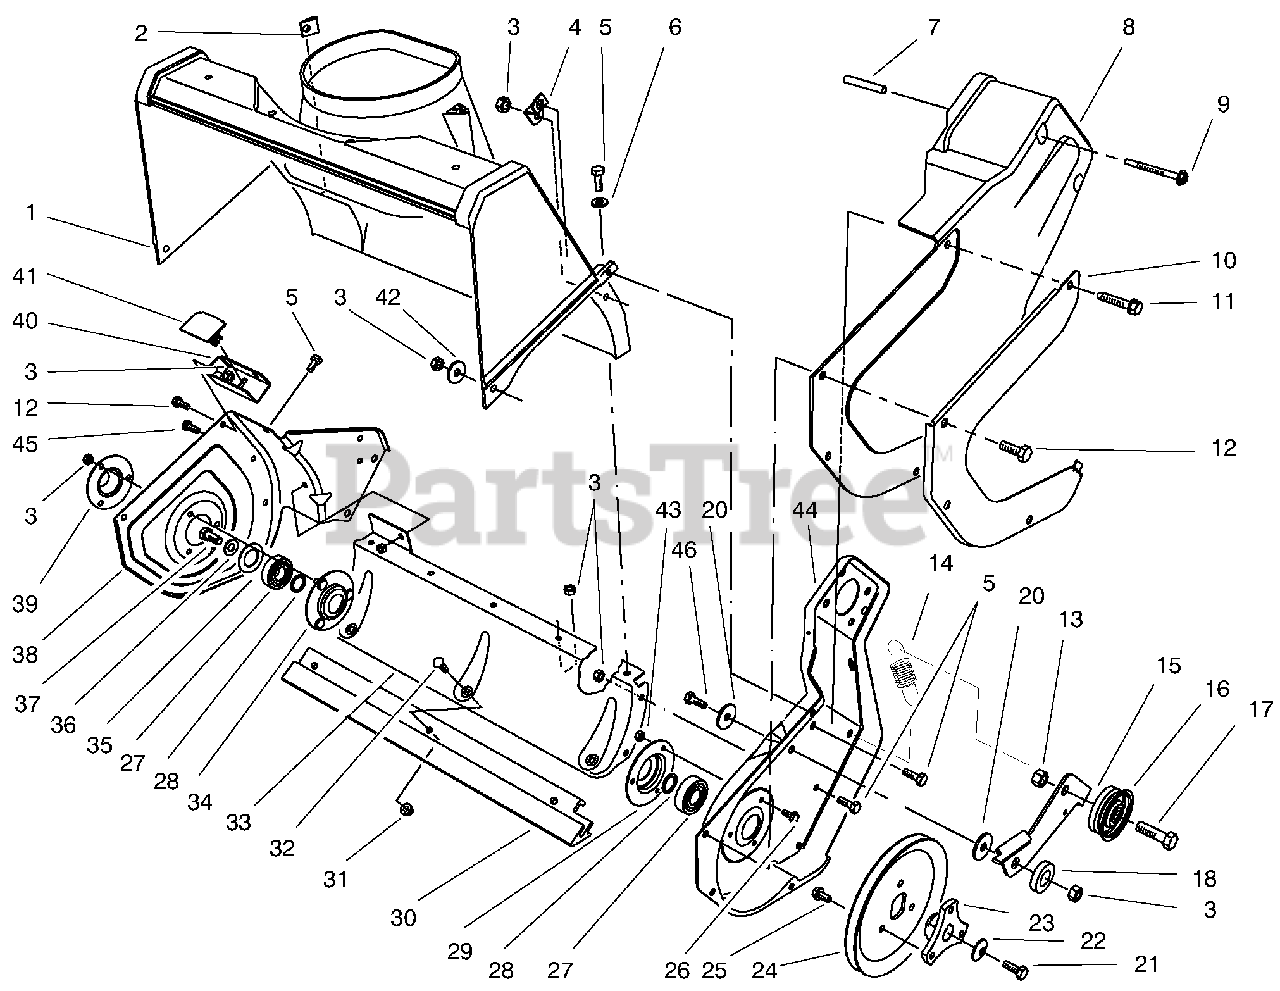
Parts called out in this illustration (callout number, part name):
1	Housing-Rotor
3	Nut-Lock
4	Bracket-Z
5	Screw-Hex. Hd.
6	Washer-Flat
8	Cover-Drive
9	Screw-Thread Forming
10	Guard-Drive Cover
11	Screw-Special
12	Screw-Hex. Flange Hd.
13	Nut-Lock
14	Spring-Brake
15	Arm-Brake
16	Pulley-Idler
17	Screw-Hex. Hd.
18	Washer-Spacer
21	Screw-Hex. Hd.
22	Washer-Belleville
23	Hub-Pulley
24	Pulley-Rotor
25	Screw-Hex. Flange Hd.
26	Screw-Hex. Hd.
27	Bearing-Ball
28	Washer-Thrust
29	Flange-Bearing
31	Nut-Flange Lock
32	Bolt-Carriage
33	Housing-Lower
34	Flange-Bearing
35	Washer-Rubber
36	Washer-Flat
37	Screw-Hex. Hd.
38	Sideplate-R.H.
39	Retainer-Bearing
40	Bracket-Support
41	Cover-Bracket
42	Washer-Flat
43	Nut-Lock
44	Sideplate-L.H.
45	Screw-Hex. Washer Hd.
46	Screw-Hex Hd. Cap
